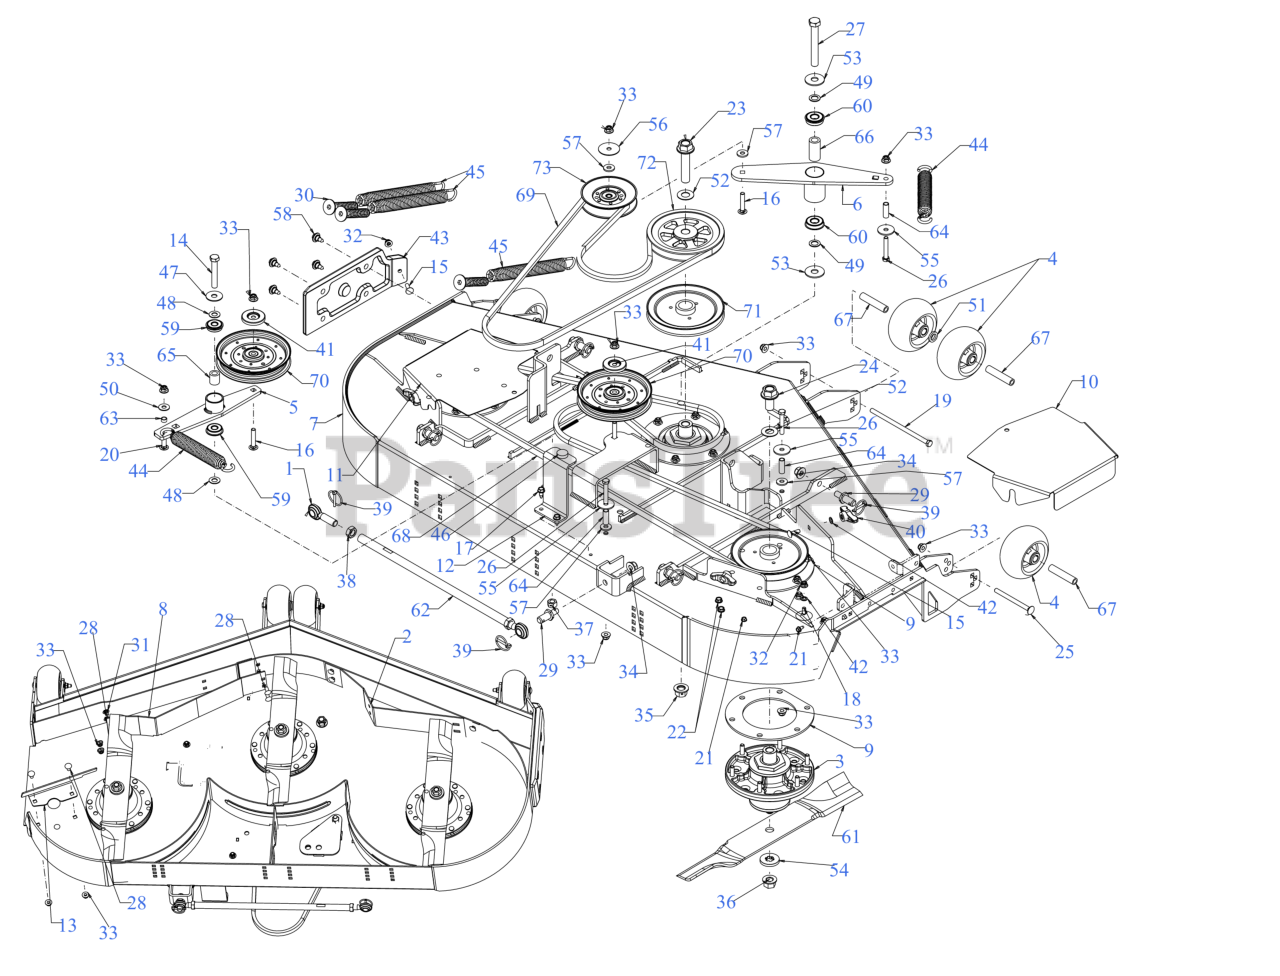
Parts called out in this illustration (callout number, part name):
1	MALE ROD END
2	BAFFLE - 60" ADJ
3	SPINDLE ASSEMBLY
4	5" DIA DECK WHEEL COMPLETE
5	IDLER BRACKET
6	IDLER BRACKET
7	60" FAB DECK SHELL
9	SPINDLE SUPPORT BRACKET TOP/BTM
10	BELT COVER (RH)
11	BELT COVER (LH)
12	DECK STOP BRACKET
13	60" DECK CHUTE BAFFLE
14	SCREW-HEX 1/2-13 x 3.00
15	CARRIAGE BOLT 5/16-18 x 1.00
16	CARRIAGE BOLT 3/8-16 x 2
17	SCREW 5/16-18 x .750
18	CARRIAGE BOLT 5/16-18 x .75
19	SCREW 3/8-16 x 7.25 GR5
20	CARRIAGE BOLT 3/8-16 X1.25 GR5
21	SCREW 1/4-20 X.500
22	SCREW 5/16-18 x .500
23	CAP SCREW-HHFLG 3/4-10 X 3.50 GR8
24	CAP SCREW-HHFLG 3/4-10 X 1.50 GR8
25	CARRIAGE BOLT 3/8-16 x 4.25 GR5
26	SCREW 3/8-16 x 2.25 GR5
27	SCREW 5/8-18X4.5 GR5
28	CARRIAGE BOLT 3/8-16 x .75
30	SPRING INSERT SCREW
32	FLANGE LOCK NUT 5/16-18
36	FLANGE NUT - 5/8-18 GDE 8
37	HEX NUT CTR LK 1/2-13
38	HEX JAM NUT 5/8-18
39	LYNCH PIN .1875
40	WING KNOB 5/16-18
41	PULLEY CAP
43	DECK SKID PLATE (LH)
44	SPRING 1.25" DIA x 8.5" LONG
45	EXTENTION SPRING 1.20 x 11.35
46	RUBBER BUMPER 1.000 x .313
47	FLAT WASHER
48	FLAT WASHER .510X.995
49	FLAT WASHER
50	WASHER-.395 x 1.0 x .62
51	FLAT WASHER .632X1.00X.16
52	FLAT WASHER
53	FLAT WASHER 0.635xX1.755x0.110
54	FLAT WASHER - SPECIAL
55	FLAT WASHER .406X1.5X11
56	HUB CAP WASHER .406 x 1.92 x .060
57	FLAT WASHER .406ID X1.0 OD
58	SHOULDER SCREW .43X.29X5/16-18 TT
59	ROLLER BEARING .5X1.37X.44
60	BALL BEARING W/RET
61	21" BLADE (HI LIFT)
61	Cub Cadet 60" BLADE SET
61	Genuine Factory Parts 60" BLADE SET
61	LOW-LIFT 21"BLADE (60"DECK)
61	BLADE-HI LIFT 21.0
61	BLADE-21"MULCH 60"
61	21" XTREME BLADE
62	TUBE .565 X .750 X 18.75"LG
65	SPACER 0.51 x 0.88 x 1.00
66	SPACER 0.63 x 1.00 x 2.01
67	WHEEL SPACER .38ID x 3.04LG
69	BELT B SEC x 94.25
70	IDLER PULLEY
71	SPINDLE PULLEY 7"
72	PULLEY-7.01 OD x .75 ID
73	IDLER PULLEY 5.06 OD
